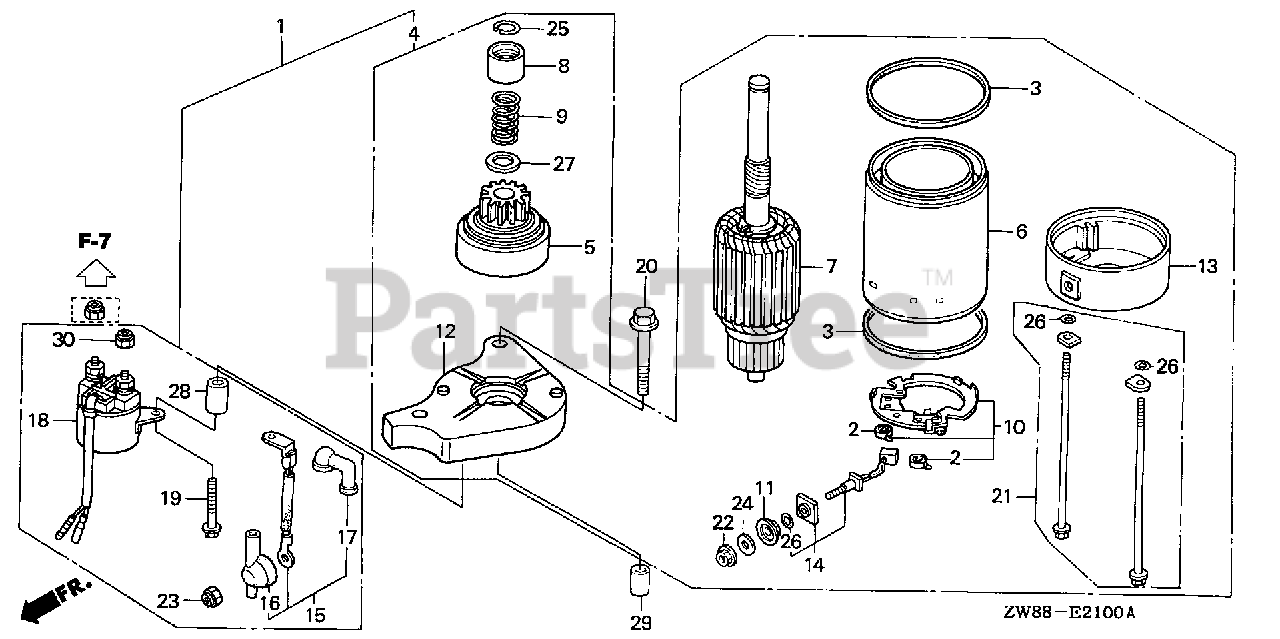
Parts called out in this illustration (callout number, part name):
1	STARTER MOTOR ASSY.
2	SPRING, CARBON BRUSH
4	STARTER MOTOR UNIT
8	PIECE, STOPPER
9	SPRING, RETURN
10	HOLDER, BRUSH
12	BRACKET, FR.
13	BRACKET, RR.
14	TERMINAL UNIT
15	WIRE, MAGNETIC SWITCH
16	COVER, STARTER TERMINAL
17	COVER, MAGNETIC SWITCH TERMINAL
18	SWITCH ASSY., STARTER MAGNETIC
19	BOLT, FLANGE (6X14)
19	BOLT, FLANGE (6X18)
20	BOLT, FLANGE (8X45)
21	BOLT, SETTING
22	NUT-WASHER (6MM)
23	NUT, LOCK (6MM)
24	WASHER (6MM)
25	CIRCLIP (14MM)
26	O-RING (4X2)
28	COLLAR, DISTANCE
29	PIN, DOWEL (10X12)
30	NUT, LOCK (6MM)
